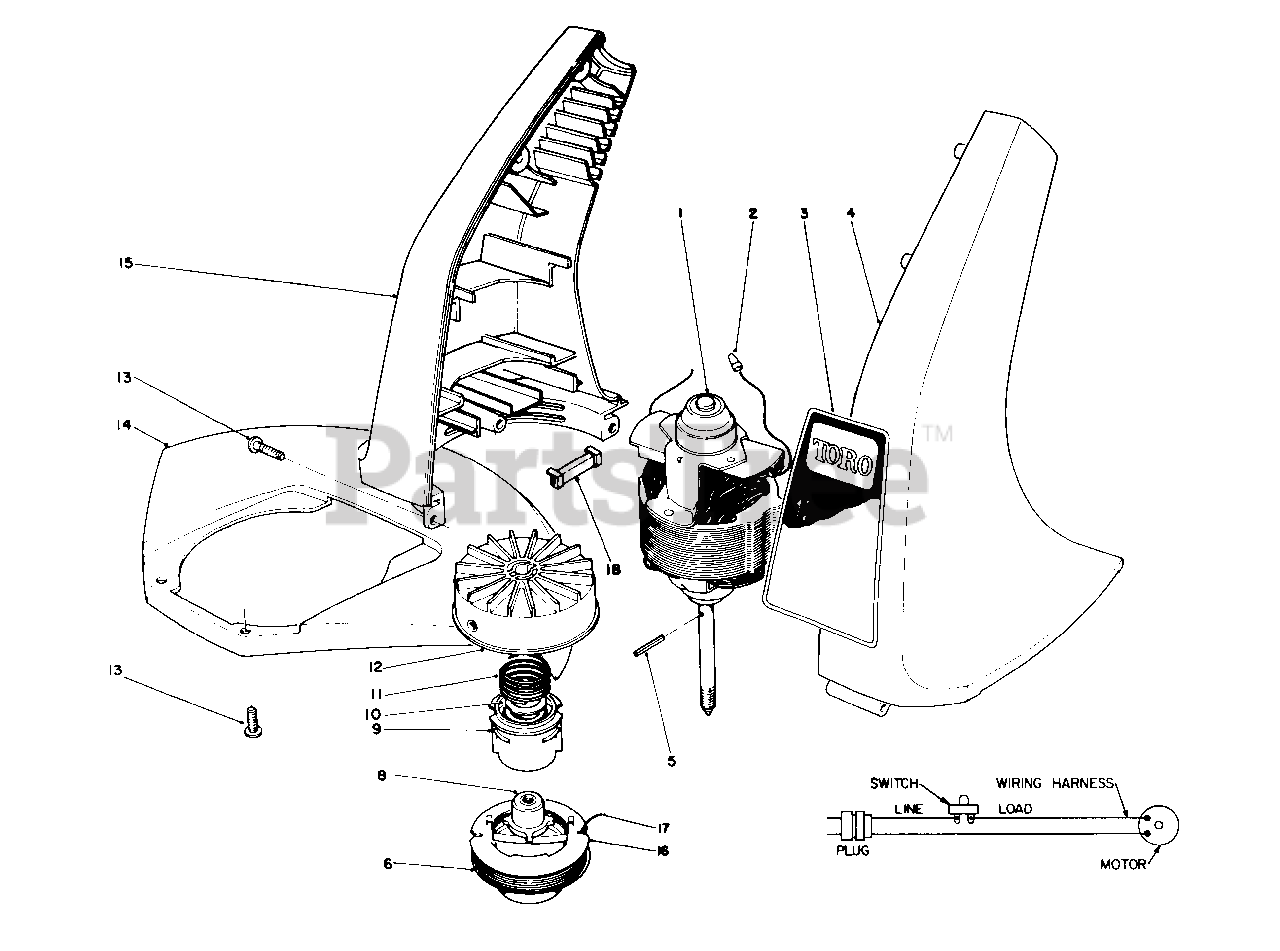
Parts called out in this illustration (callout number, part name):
2	Connector-Wire
3	Decal-12 Inch
4	Housing-L.H.
6	50 Ft. .065 Dia. Cutting Line Prewound on Spool
12	Drum w/Eyelet
13	Screw
15	Housing-R.H.
16	Empty Spool
17	50 Ft. Coil-.065 Dia. Cutting Line in Coil
18	Insert-Housing
